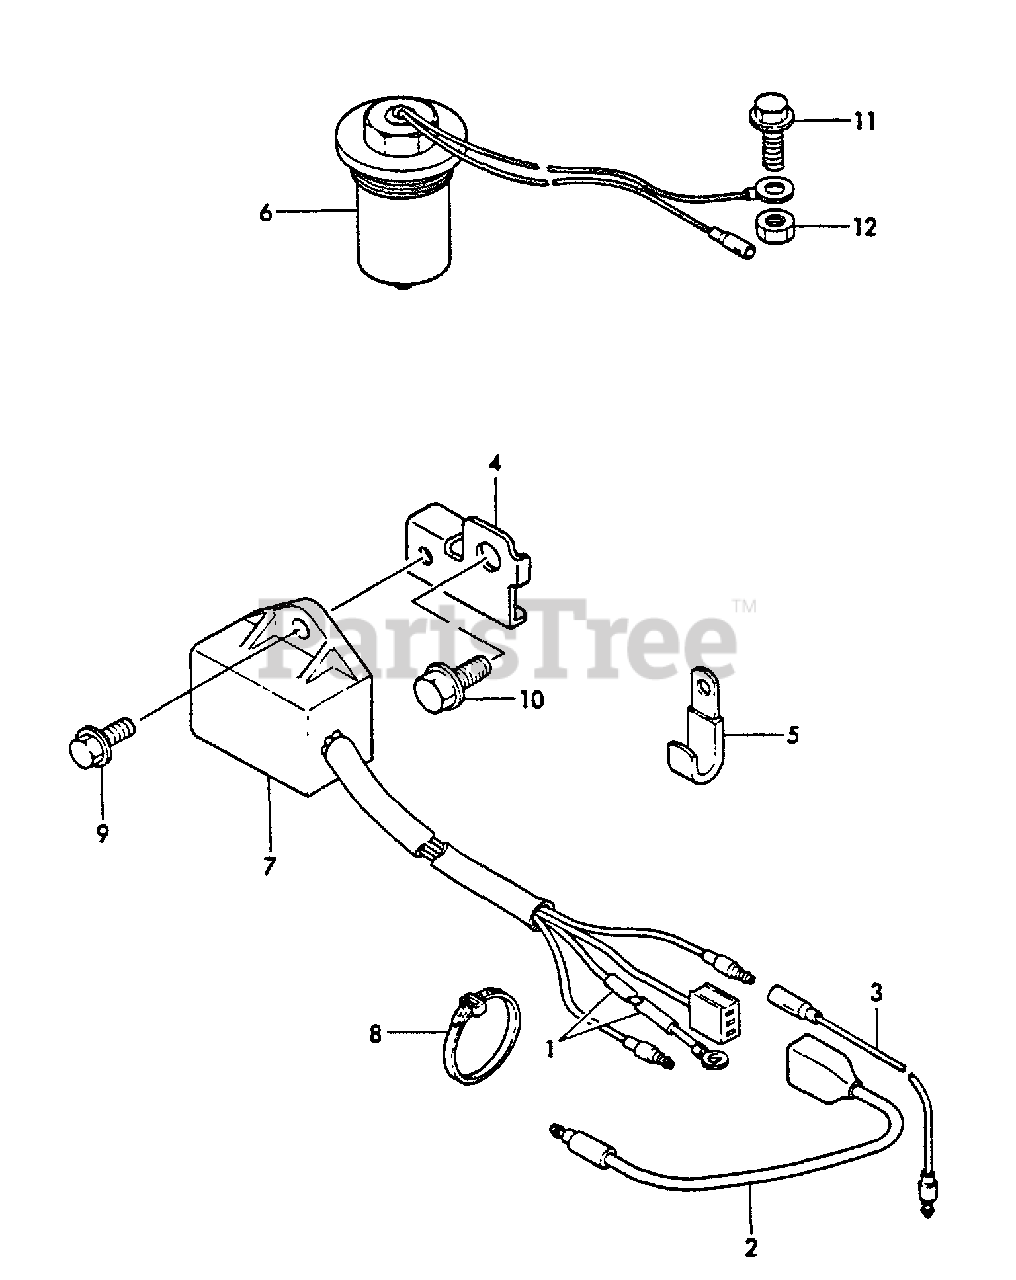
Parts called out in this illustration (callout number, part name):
1	TUBE, INSULATOR
2	WIRE
3	WIRE, SENSOR UNIT
4	STAY, SENSOR UNIT
5	CLAMP
6	SENSOR, OIL LEVEL
7	SENSOR UNIT, OIL
8	CLAMP
9	BOLT - 6×12 -- PLATED
10	BOLT - 8×14 -- PLATED
11	BOLT - 6×16 -- PLATED
12	LOCKNUT - 6 -- PLATED
